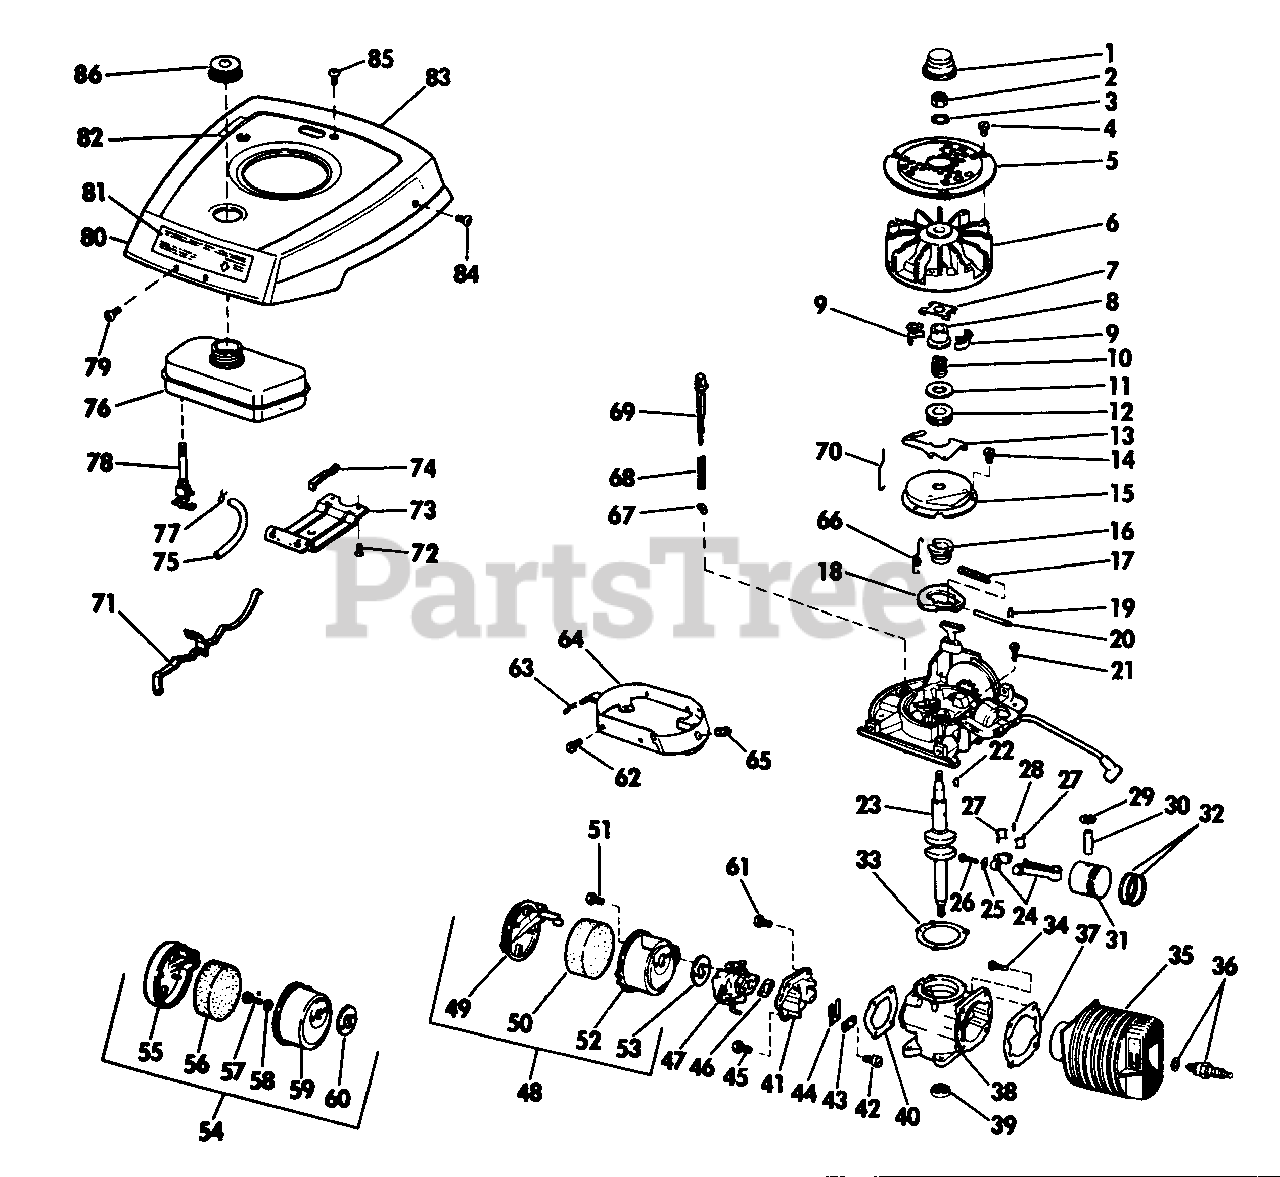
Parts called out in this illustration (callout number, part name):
2	Nut-Flywheel
3	Lockwasher-Flywheel
4	Screw-Thd. Cutting
6	Flywheel Assembly
7	Yoke-Governor
8	Collar-Governor
9	Weight-Governor
10	Spring-Governor
11	Thrust Washer
12	Collar-Thrust
13	Lever-Governor
14	Screw-Attach Dust Cover
15	Dust Cover
16	Cam-Spark Advance
17	Spring-Spark Advance
18	Flyweight-Spark Advance
19	Retainer-Spring
20	Pin-Spark Advance
21	Scr.-Arm. Pl. to Crankcase
22	Key-Crankshaft
23	Crankshaft
24	Connect Rod Assy.
25	Lockpl.-Connect Rod Scr.
26	Screw-Connect Rod
27	Liners-Connect Rod
28	Needle Brg. Set
29	Retaining Ring
30	Wrist Pin
32	Ring Set
33	Gasket-Crkc to. Arm Pl. .005 in.
33	Gasket-Crkc to. Arm Pl. .010in.
34	Screw-Cyl. to Crankcase
35	Cylinder and Sleeve Assembly
36	Spark Plug and Gasket
37	Gasket-Cyl. to Crankcase
38	Crankcase and Seal Assy.
39	Oil Seal
40	Gasket-Reed Plate
41	Reed Plate Assembly
42	Screw-Machine
43	Plate-Back-up
45	Screw-H.H. Reed Pl. to Crkc.
46	Gasket-Carburetor
47	Carburetor Assembly
48	Air Filter Assembly (Metal)
49	Cover and Spring Assembly
50	Element-Air Filter
51	Screw-Filter to Carb.
52	Chamber-Filter
53	Gasket, Drain
54	Air Filter Assy.
55	Cap (Plastic)
56	Element-Air Chamber
59	Chamber-Air (Plastic)
61	Screw-H.H. Reed Pl. to Crkc.
62	Screw-Baffle
63	Nut-Cover Mtg.
64	Air Baffle Assy.
65	Grommet-Cover Mtg.
66	Spring-Variable Speed
67	Blade-Switch
68	Spring-Shut-Off Switch
69	Bar-Shut-Off and Primer
70	Rod-Governor
71	Control and Guide-Variable Speed
73	Bracket-Fuel Tank
74	Spring-Fuel Tank
75	Gas Line
76	Fuel Tank
77	Hose Clip-Fuel Tank
78	Shut-Off Valve & Screen Assy.
79	Screw-Shroud Mtg.
80	Engine Cover Assy.
81	Decal-Instructions
82	Decal-On-Off; Prime
83	Decal-Lawn-Boy
84	Screw-Cover Mounting
85	Screw-Cover to Starter Boss
86	Cap-Gas Tank (Plastic)
